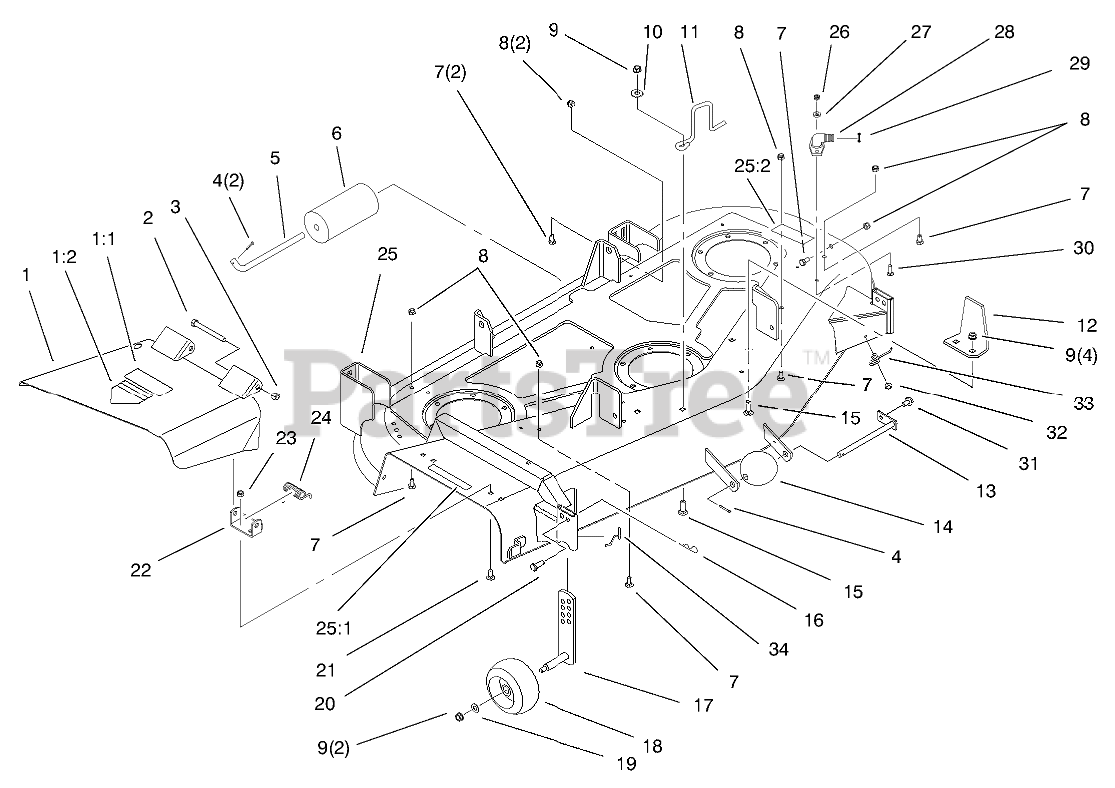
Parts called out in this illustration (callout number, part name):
1	Deflector ASM (Only On: 78370, 78375)
1	Deflector ASM (Only On: 78452)
1:1	Decal-Danger (Only On: 78370, 78375)
1:1	Decal-Danger (Only On: 78452)
1:2	Decal-Danger (Only On: 78370, 78375)
1:2	Decal-Danger (Only On: 78452)
2	SCREW-HH
3	NUT-HEX
4	PIN-COTTER
5	SHAFT-ROLLER, REAR
6	ROLLER-DECK
7	Screw-HH (Only On: 78370, 78452)
8	Nut-Lock (Only On: 78370, 78452)
9	NUT-LOCK, NI
10	WASHER
11	GUIDE-BELT
12	Bracket Guide
13	SHAFT ASM
14	ROLLER
15	BOLT-CARR
16	PIN-HAIR
17	GAGE-WHEEL
18	WHEEL-GAGE
19	WASHER-FLAT
20	PIN-CLEVIS
21	SCREW-CARR
22	BRACKET-PIVOT
23	NUT-LOCK, NI
24	SPRING
25	Deck ASM (Only On: 78370, 78375)
25	Deck ASM (Only On: 78452)
25:1	Decal-Danger (Only On: 78370, 78375)
25:1	Decal-Deflector Danger (Only On: 78452)
25:2	Decal-Danger (Only On: 78370, 78375)
25:2	Decal-Danger (Only On: 78452)
26	Nut-Lock (Only On: 78452)
27	Washer-Flat (Only On: 78452)
28	Fitting-Washout (Only On: 78452)
29	0-Ring (Only On: 78452)
30	Bolt-CARR (Only On: 78452)
31	SCREW-HWHTF
32	SCREW-HHFTF
33	SPRING-GAGE WHEEL, LH
34	SPRING-GAGE WHEEL, RH
